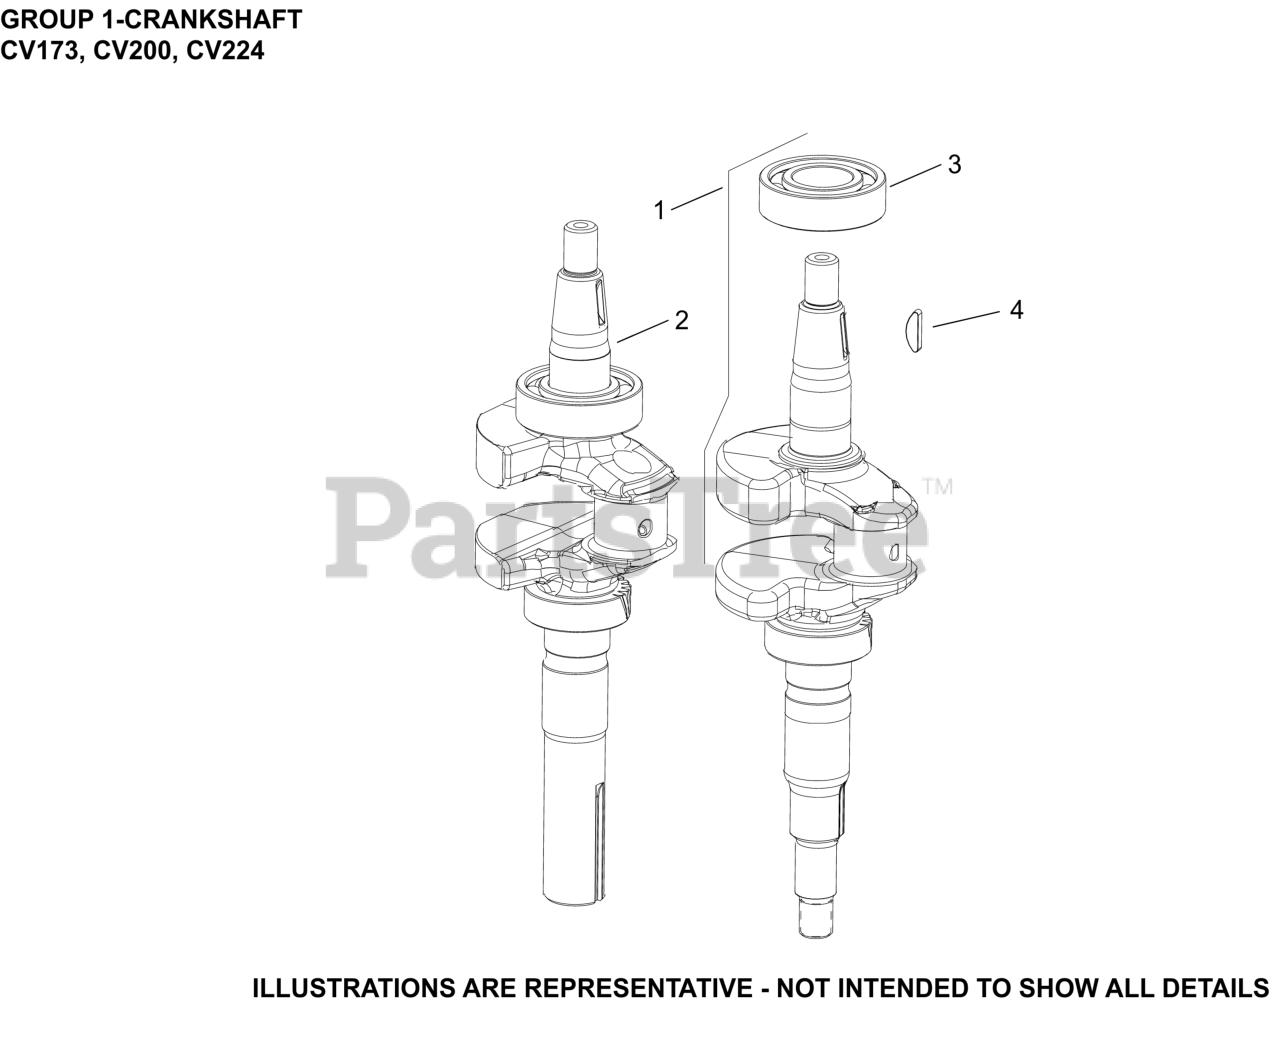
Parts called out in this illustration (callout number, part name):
2	CRANKSHAFT, ASSEMBLY
3	BEARING, BALL
4	KEY, FLYWHEEL
